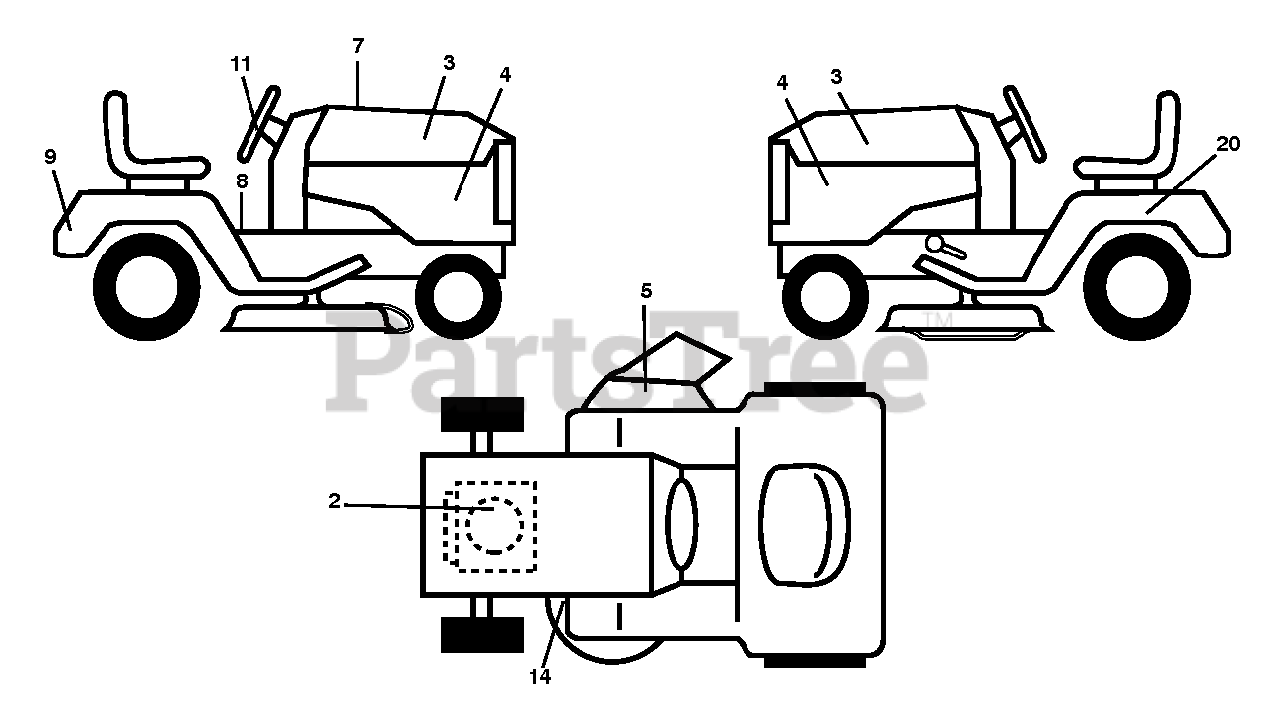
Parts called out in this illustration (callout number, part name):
2	Decal, Engine BS 18 5INTK 381713
3	DECAL.POULAN PRO.2015
4	Decal, Side Panel PB185A42 BLK PPRO
5	DECAL, DECK DEFLECTOR, WARNING
7	DECAL DECAL.RPL.BSM33.INTK.LT.
8	DECAL.FENDER.WARNING.ENGLISH
9	DECAL.REARFNDR.POULAN PRO.2015
11	Decal, Steering Wheel STDXXSQ PPRO 2015
14	DECAL.V-BELT.SCH.42/46"MEC/ELE
20	DECAL BTRY SYMBOLS
